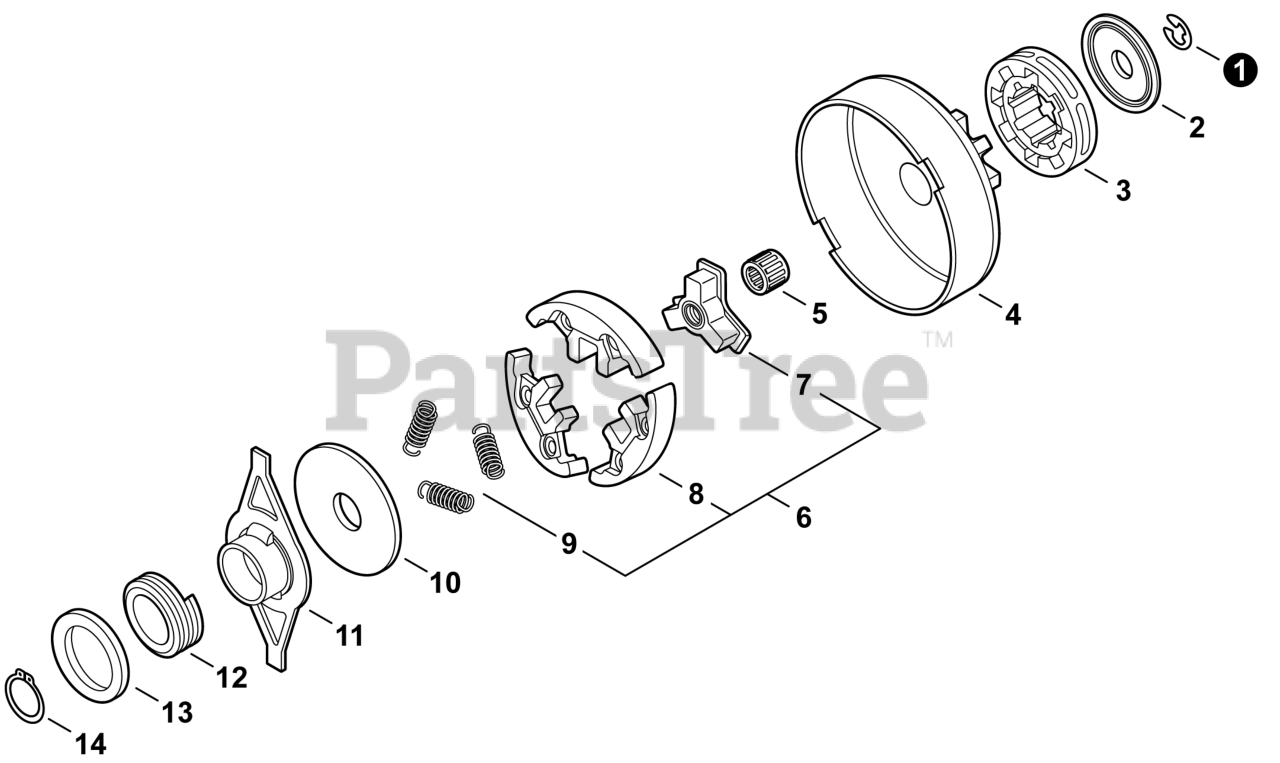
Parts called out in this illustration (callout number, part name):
1	E-RING 8.1
2	WASHER 10
3	SPROCKET, RIM 3/8"x7T
4	DRUM, CLUTCH
5	BEARING, NEEDLE 10
6	CLUTCH ASSY
7	HUB, CLUTCH
8	CLUTCH SHOE SET (3PCS)
9	SPRING, TENSION
10	PLATE, CLUTCH
11	COLLAR 15x19x73
12	GEAR, WORM
13	WASHER 15.5x22.5x0.5
14	RING, RETAINING 15
